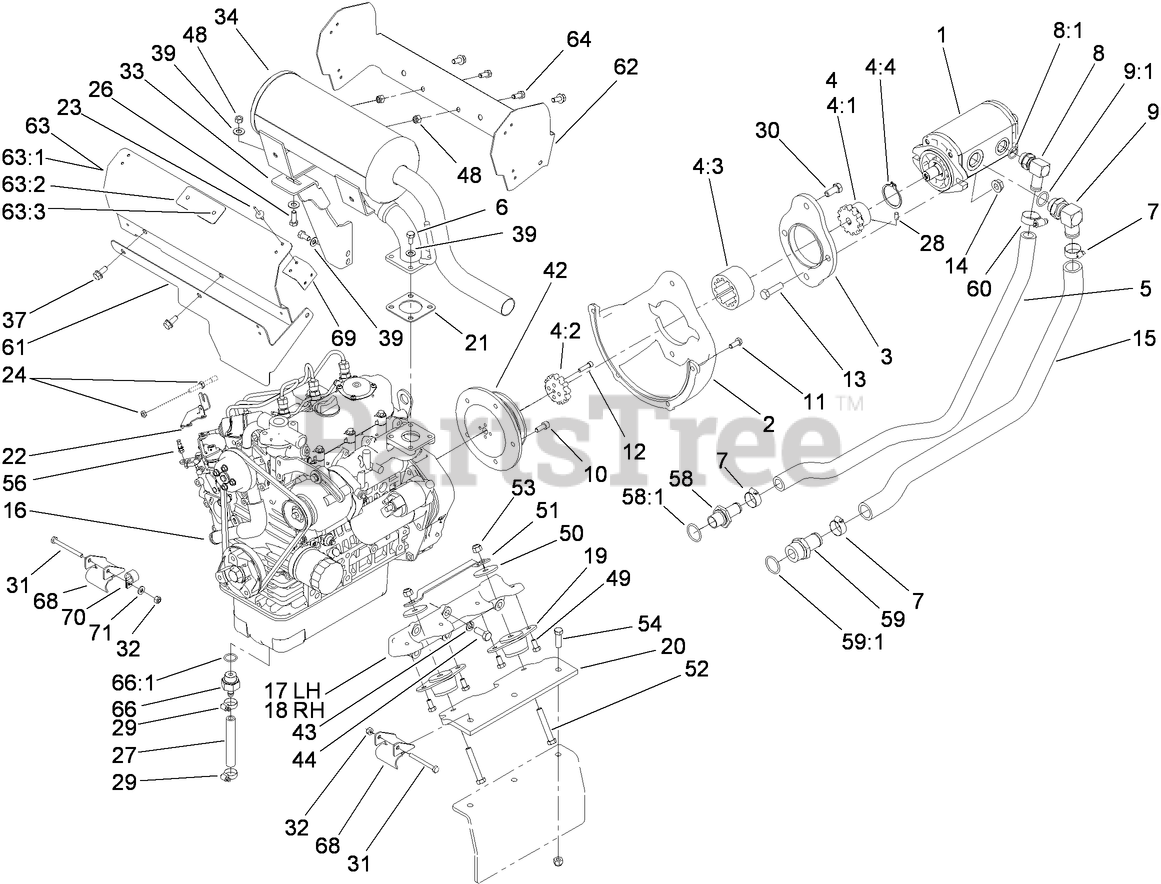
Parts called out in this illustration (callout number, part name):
1	PUMP-HYD
2	PUMP-MOUNT
3	PLATE-MOUNT, PUMP
4	COUPLING ASM
4:1	HUB-COUPLING
4:2	SLEEVE-HUB
4:3	SLEEVE-COUPLING
4:4	RING-SNAP, COUPLING
5	HOSE-FORMED, SUCTION
6	BOLT
7	CLAMP-HOSE
8	FITTING
8:1	O-RING
9	FITTING-HYD, 90 DEG
9:1	O-RING
10	SCREW-CAP, HSH
11	SCREW-HH
12	SCREW-HSH
13	SCREW-HH
14	NUT-HF
15	HOSE-FORMED, SUCTION
16	ENGINE-KUBOTA, D902
17	MOUNT-ENGINE, LH
18	MOUNT-ENGINE, RH
19	MOUNT-ENGINE
20	PLATE-MOUNT, ENGINE
21	GASKET-MUFFLER
22	BRACKET-SUPPORT, THROTTLE
23	RIVET
24	NUT-JAM
26	SCREW-HH
27	HOSE-DRAIN, ENGINE OIL
28	SCREW-SET, HSH
29	CLAMP-HOSE
30	SCREW-HH
31	SCREW-HH
32	NUT-LOCK, CONE
33	SUPPORT-MUFFLER
34	MUFFLER ASM
37	SCREW-HHF
39	WASHER-PLAIN
42	PULLEY
43	WASHER-LOCK, SPRING
44	SCREW-HH
48	NUT-LOCK, CONE
49	SCREW-HH
50	WASHER-REBOUND
51	STRAP-REBOUND
52	SCREW-HH
53	NUT-LOCK, NI
54	SCREW-HH
56	SWIVEL-STOP, CABLE
58	FITTING-HOSE, BARBED
58:1	O-RING
59	FITTING-STR
59:1	O-RING
60	CLAMP-HOSE
61	PLATE-BAFFLE, LOWER
62	PLATE-BAFFLE
63	HEAT SHIELD BAFFLE ASM
63:1	PLATE-BAFFLE, MUFFLER
63:2	PLATE-HOT SURFACE
63:3	RIVET-POP
64	SCREW-HH
66	FITTING-HOSE
66:1	GASKET
68	GUIDE-CABLE
69	BRACKET-SHIELD
70	CLAMP-CABLE
71	WASHER-FLAT
